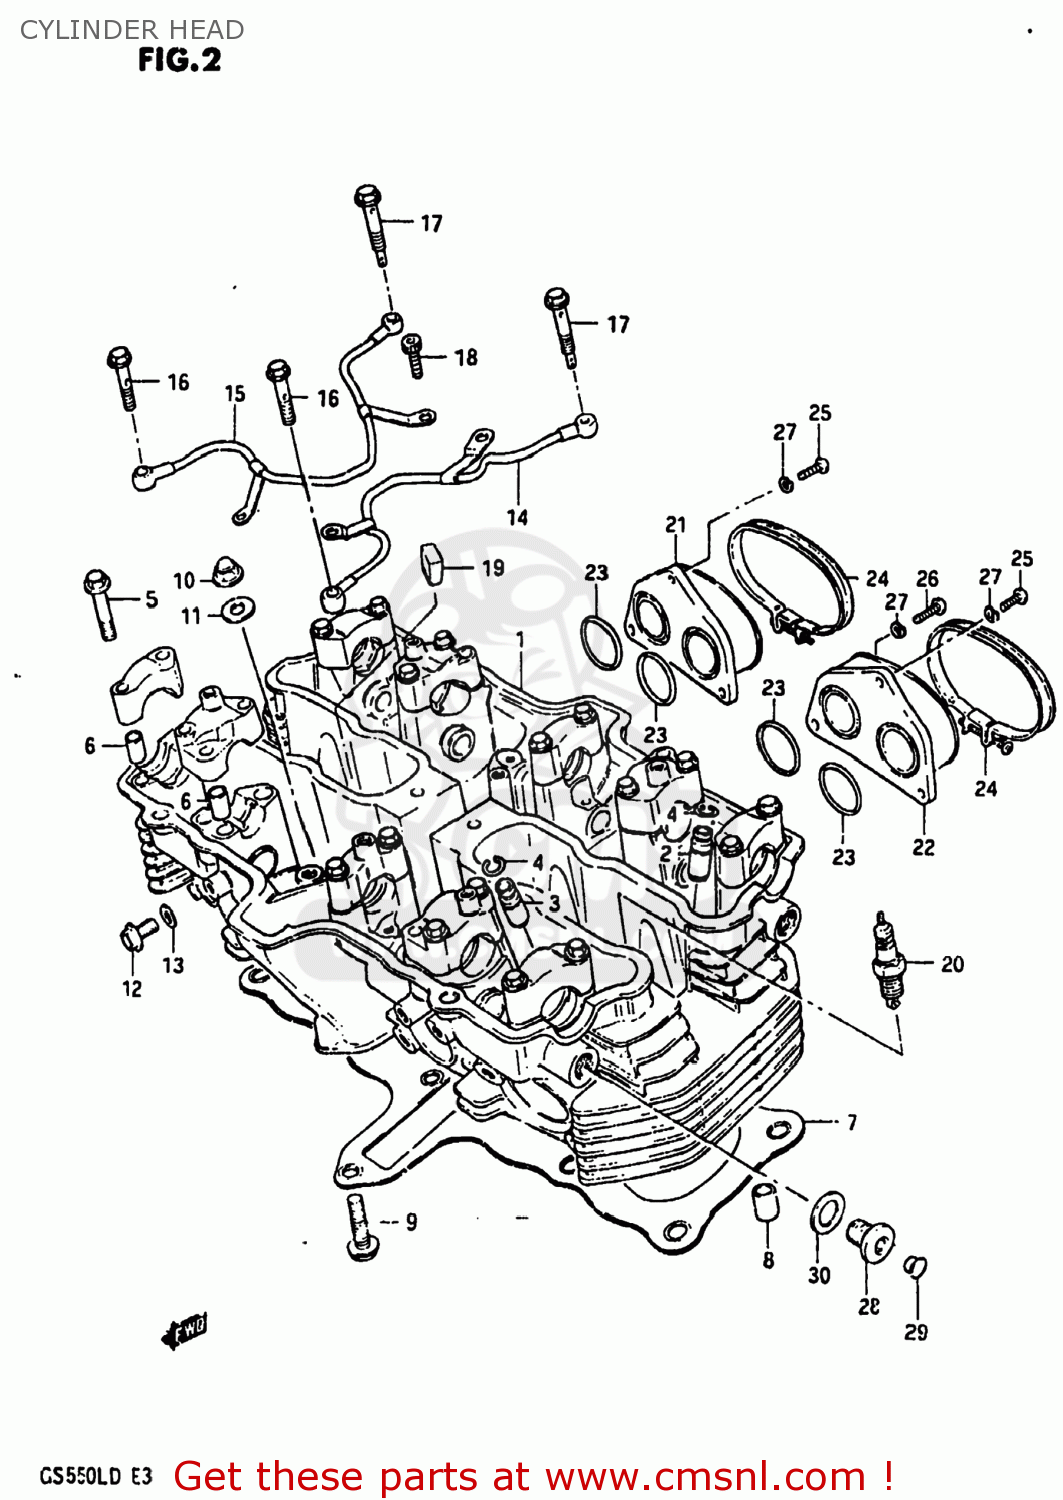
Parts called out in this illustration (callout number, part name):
1	HEAD ASSEMBLY,CYLINDER
2	GUIDE,VALVE
3	GUIDE,VALVE
4	RING,SNAP
5	BOLT(6X39)
6	PIN(6.2X8X11)
7	GASKET,CYLINDER HEAD (NAS)
8	PIN
9	BOLT
10	NUT
11	GASKET(8.5X20X2.3) (NAS)
12	BOLT 6X12
13	GASKET(6.2X13X1.2) (NAS)
14	PIPE,OIL CYLINDER HEAD
15	PIPE,OIL CYLINDER HEAD
16	UNION
17	BOLT,UNION
18	BOLT
19	PAD,CYLINDER
20	SPARK PLUG D9EA
21	PIPE,INTAKE,RIGHT
22	PIPE,INTAKE,L
23	O-RING (D:2.4 ID:29.7)
24	CLAMP
25	SCREW
26	SCREW
27	LOCK WASHER
28	PLUG,14X12
29	CAP(OD:12)
30	GASKET(14X19.2X2) (NAS)
